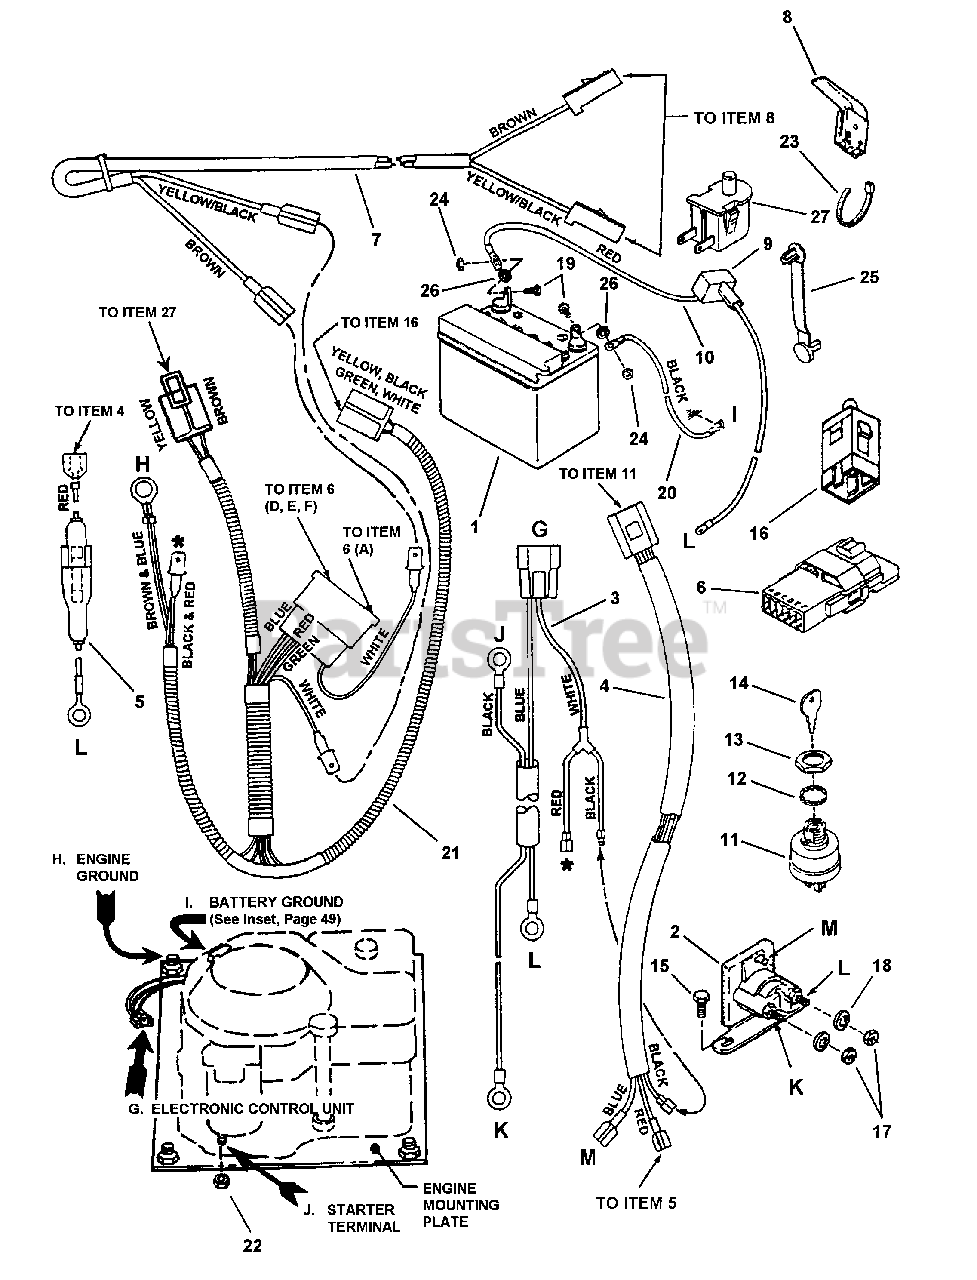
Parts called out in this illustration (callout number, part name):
1	KIT, Battery, 12V, U-1-7RS, 220CCA Dry Charge Snapper No Spill
2	SOLENOID
3	HARNESS, Starter Wiring
4	HARNESS, Ignition Wiring
5	HOLDER, Fuse
6	INTERLOCK Module
7	HARNESS, (Deck Interlock Wiring)
8	SWITCH, Deck Interlock (NO)
9	COVER, Battery Cable
10	CABLE, Positive (Red) (17" Long)
11	SWITCH, Ignition (Includes keys #11138)
12	WASHER, 5/8" Internal Tooth Lock
13	NUT, 5/8-32 Hex
14	KEY, Switch
15	SCREW, 1/4-20 x 1/2" Hex Washer Self-Tap
16	SWITCH, Operator Presence Control (OPC)Traction (NC/NO)
17	NUT, 1/4-20 Hex, Grade 5 or B
18	WASHER, 1/4" Internal Tooth Lock
19	SCREW, 1/4-20 x 5/8" Hex Head Cap, Grade 5
20	CABLE, Negative (15")
21	HARNESS, Operator Presence Control Wire
22	NUT, 1/4-20 Hex, Grade 5 or B
23	TIE, 7" Long Cable
24	NUT, 1/4-20 Hex Center Lock, Grade 5 or B
25	TIE, 2" Long Cable
26	RETAINER, 1/4" Bolt
27	SWITCH, Seat (NC)
